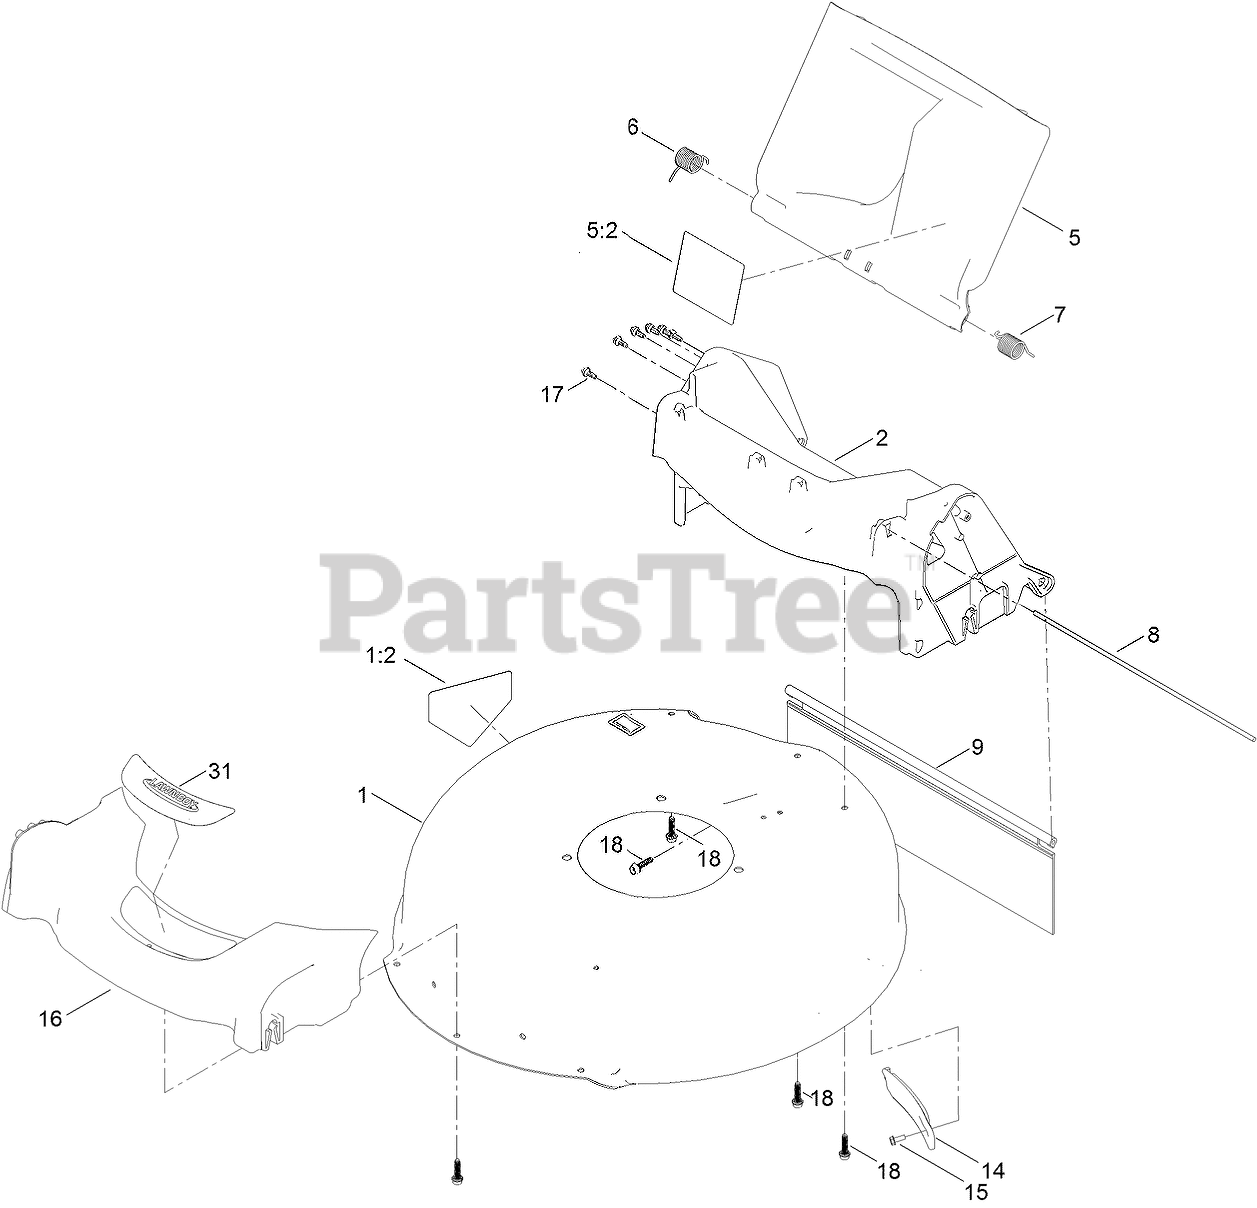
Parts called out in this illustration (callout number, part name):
1	HOUSING ASM
1:2	DECAL-DANGER
2	CHUTE ASM
5	REAR DEFLECTOR ASM
5:2	DECAL-WARNING
6	SPRING-TORSION
7	SPRING-TORSION
8	ROD-DOOR
9	SHIELD-TRAILING
14	COVER-BELT
15	SCREW-TAPTITE
16	BUMPER
18	SCREW-FLANGE, PLASTIC
31	DECAL-DECK
